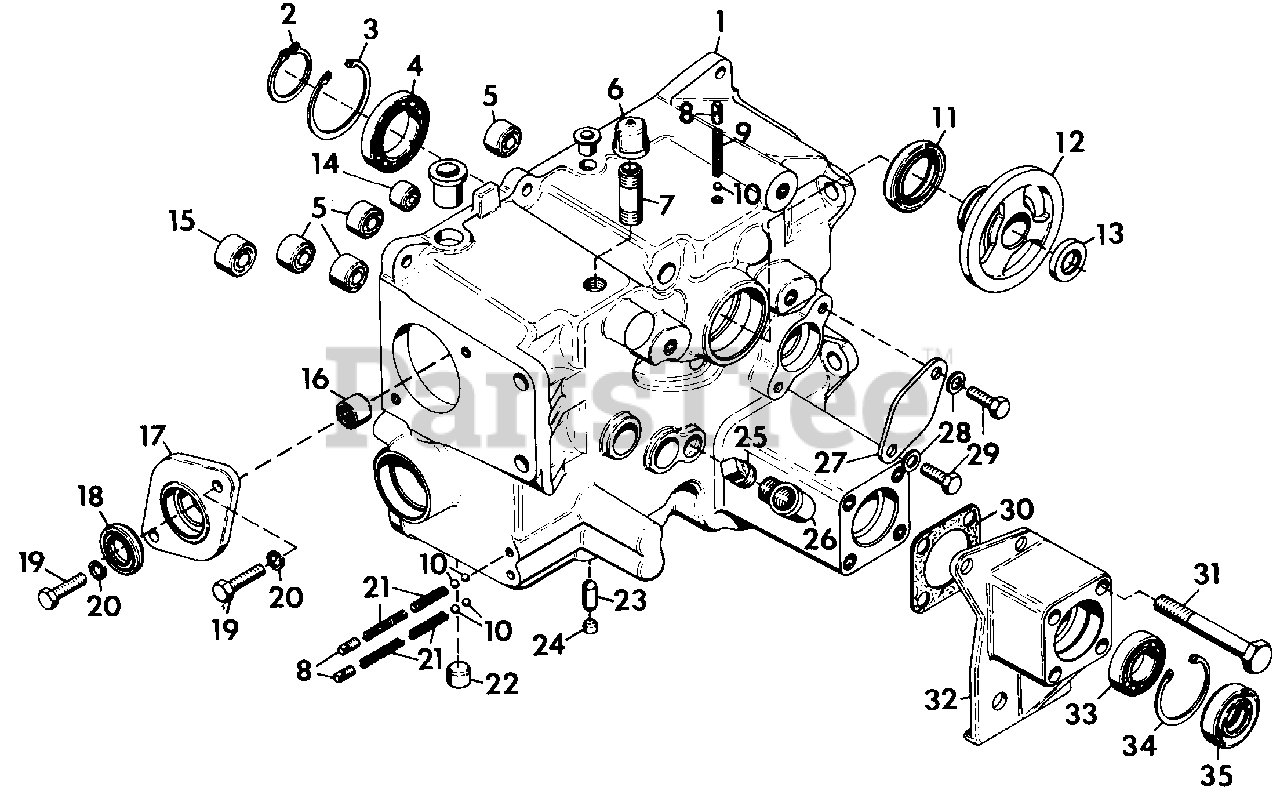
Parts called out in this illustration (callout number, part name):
1	ASSEMBLY, TRANSMISSION CASE
2	RING, RETAINING 1.969 SHAFT
3	RING, RETAINING 3.156 BORE
4	BEARING, BALL 1.968X3.149X.629
5	BEARING, NEEDLE .75X1X.75
6	CAP, PIPE 1/2 NPT
7	NIPPLE, PIPE 1/2X2.5
8	PLUG, PIPE 1/8
9	SPRING
10	BALL, STEEL 5/16
11	SEAL, OIL 2.250X3.005X.375
12	HUB, CLUTCH
13	SEAL, OIL .75X1.625X.25
14	BEARING, NEEDLE .625X.812X.750
15	BEARING, NEEDLE 1.000X1.250X.750
16	BEARING
17	CAP, FRONT PTO
18	SEAL, OIL .750X1.254X.188
19	BOLT, HEX 5/16-18X1.00
20	WASHER, LOCK 5/16 REG.
21	SPRING, COMP. 1.50X.30X26 LB/IN
22	PLUG
23	PIN, INTERLOCK
24	PLUG, CUP 3/8
25	PLUG, PIPE 1/2
26	ELBOW, 1/2 90 DEGREE STREET
27	PLATE, COVER
28	WASHER, FLAT .406X.812X.065
29	BOLT, HEX 3/8-16X.750
30	GASKET
31	BOLT, HEX 1/2-13X3.25
32	RETAINER, AXLE BEARING
33	BEARING, BALL 1.250X2.250X.500
34	RING, RETAINING
35	SEAL, OIL AXLE
